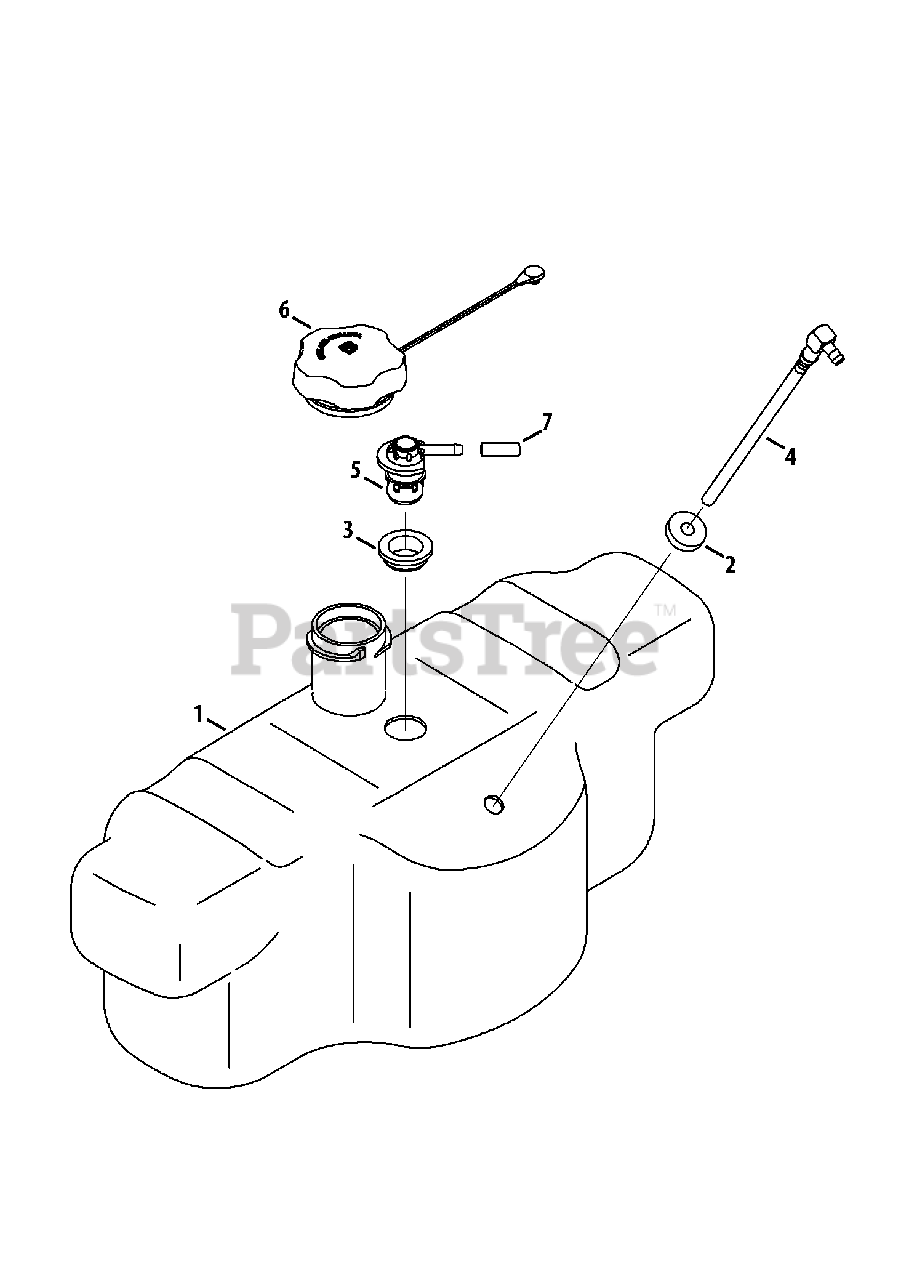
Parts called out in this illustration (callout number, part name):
1	Fuel Tank
2	Fuel Tank Bushing
3	Rubber Grommet
4	Fuel Pickup Fitting
5	Rollover Valve
